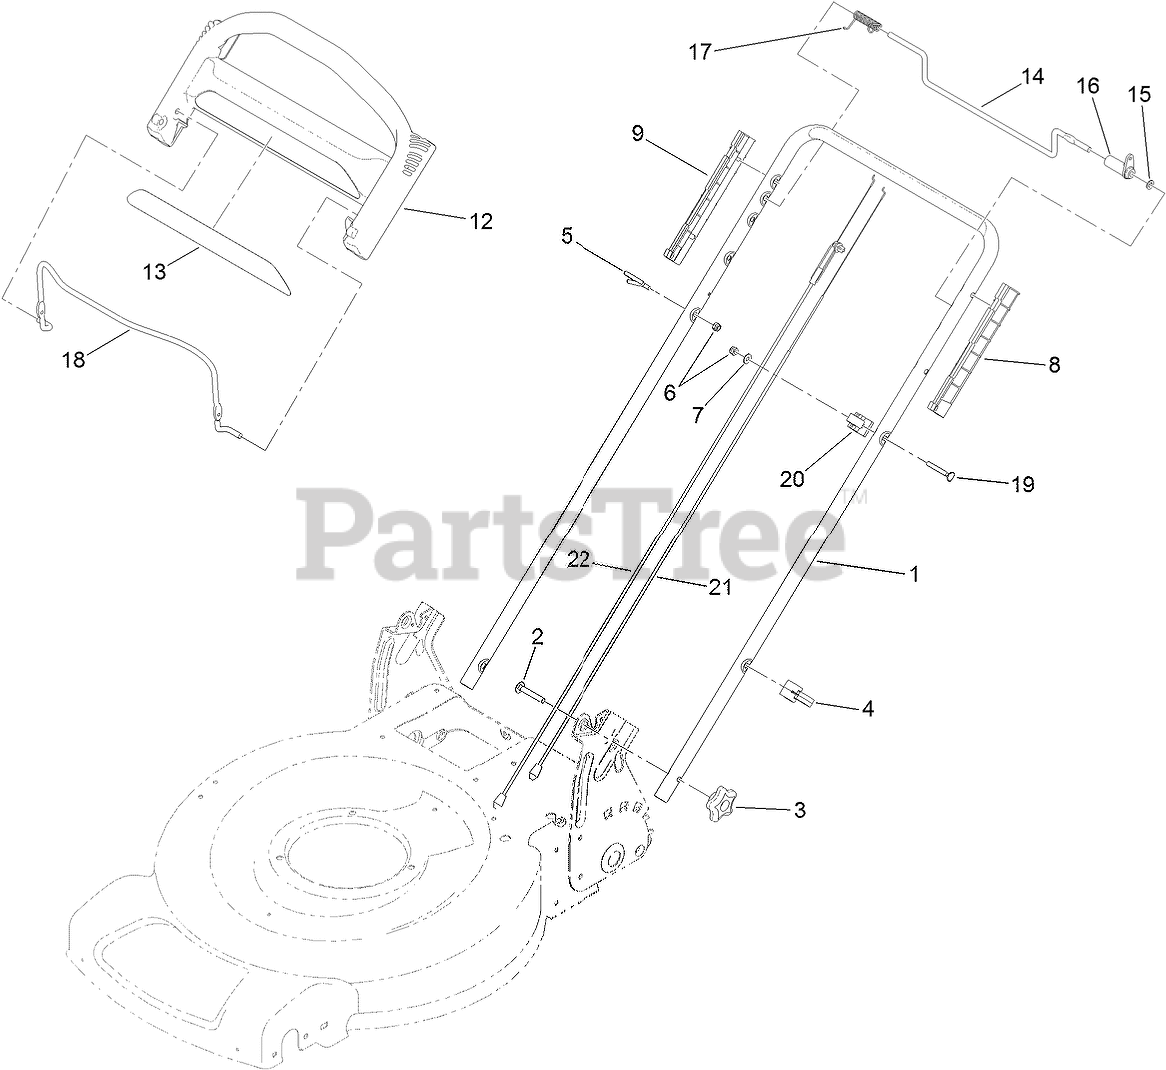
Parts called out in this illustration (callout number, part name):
2	Screw-CARR
3	KNOB-HANDLE
4	GUIDE-CABLE
5	GUIDE-ROPE
6	NUT-LOCK, NI
7	WASHER-FLAT
8	GUIDE-LH
9	GUIDE-RH
12	HANDLE-CONTROL
14	BAR-CONTROL, TRACTION
15	WASHER-PLAIN
16	LEVER-TRACTION
17	Spring-Torsion
18	Bail-Brake
19	SCREW
20	ANCHOR-CABLE
21	CABLE-TRACTION
22	CABLE-BRAKE
